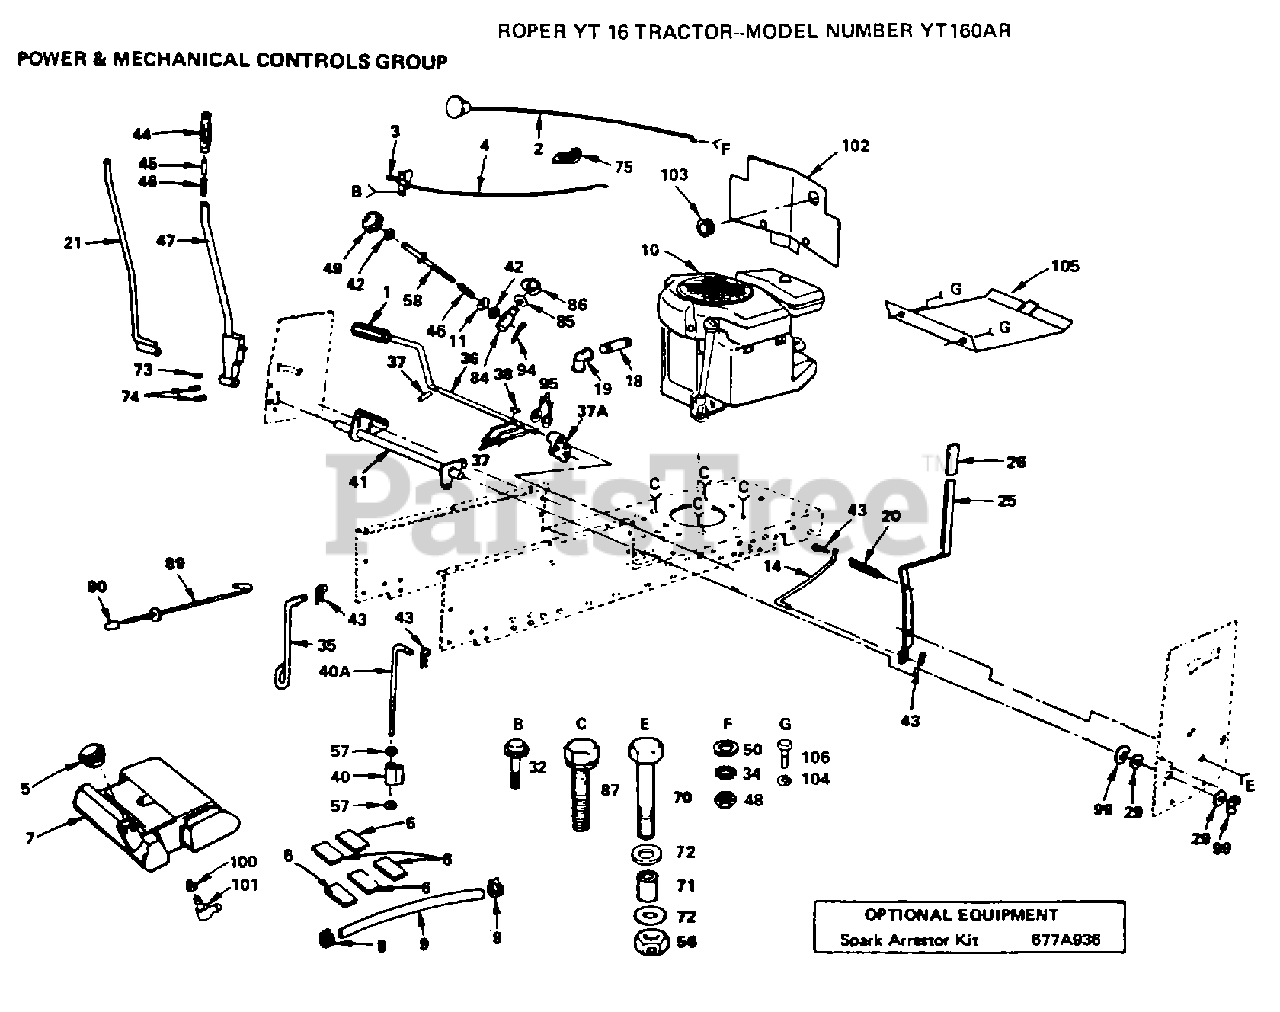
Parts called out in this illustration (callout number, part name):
1	PEDAL COVER T
4	THROTTLE CONTROL
6	PAD-SPACER T
10	ENGINE, B&S
11	WASHER
20	"SPRING.EXT.8.5"""
21	ROD ASSY-LEVER LT
25	HANDLE-CLUTCH L
29	WASHER
32	SCREW
34	LOCKWASHER
41	SHAFT ASSY YTV
42	NUT
44	HANDLE GRIP T
46	SPRING T
47	LEVER ASSY LT
50	WASHER
57	NUT.HEX.3/8-16UNC
58	ROD ADJUST LT
71	BUSHING LT
85	WASHER
86	KLIP RING
87	SCREW
90	PLUNGER CAP T
99	RING
100	BUSHING OUTLET T
101	FUEL TANK STEM GT
103	SNAP BUSHING T
104	LOCKWASHER
106	BOLT
